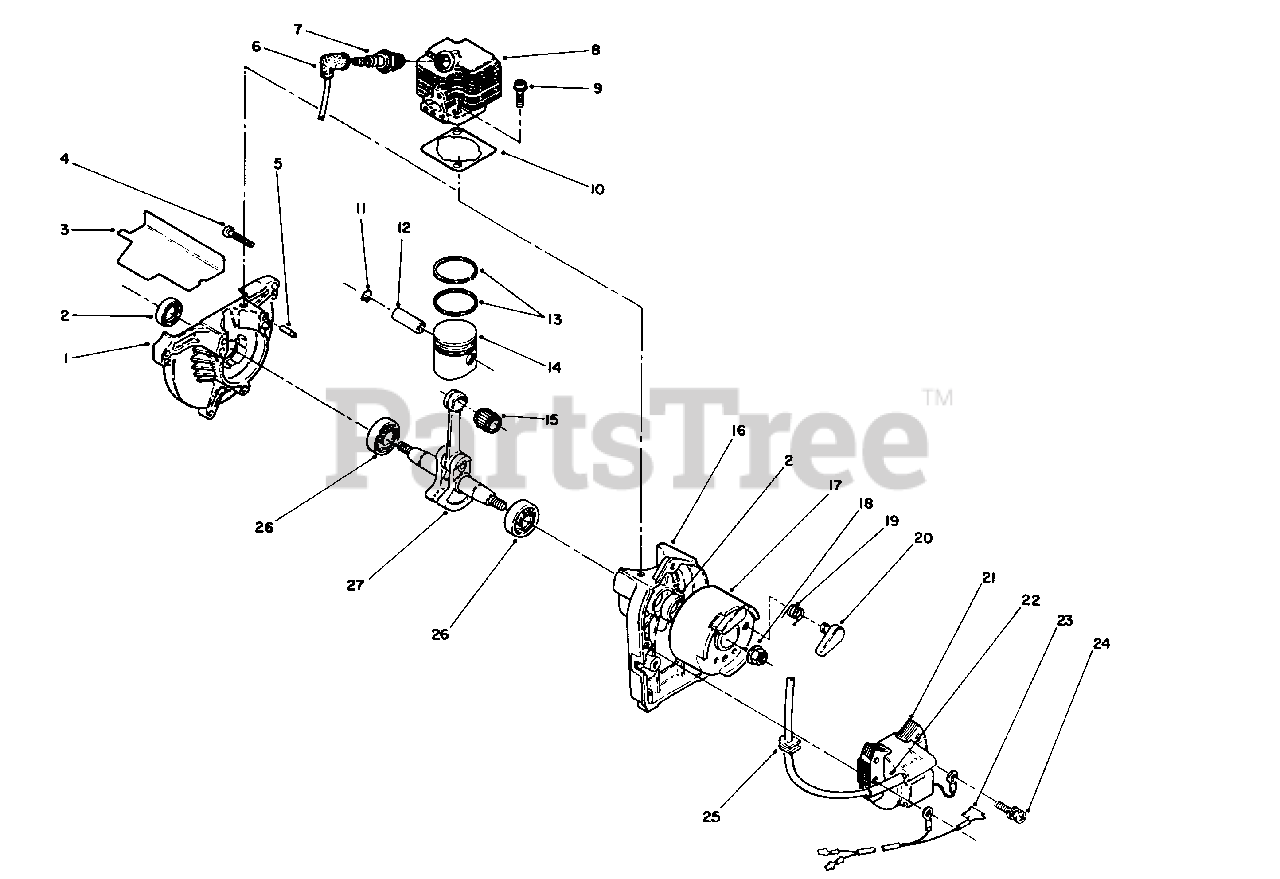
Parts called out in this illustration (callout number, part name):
1	Case-Drive
2	Seal-Oil
3	Gasket-Insulator
4	Screw-Pan Hd.
5	Pin-Dowel
6	Boot-plug
7	Plug-Spark
8	Cylinder Head
9	Bolt-Cylinder Head
10	Gasket-Cylinder Head
11	Clip-Piston Pin
12	Pin-Piston
13	Set-Piston Ring
14	Piston Assembly (Incl. Ref. #11 & 12)
15	Bearing-Needle
16	Case-Starter
17	Flywheel (Incl. Ref. #19 & 20)
18	Nut-Conical
19	Spring-Return
21	Coil-Ignition
23	Wire Assembly
24	Bolt/Washer
26	Bearing-Main
27	Crankshaft Assembly
